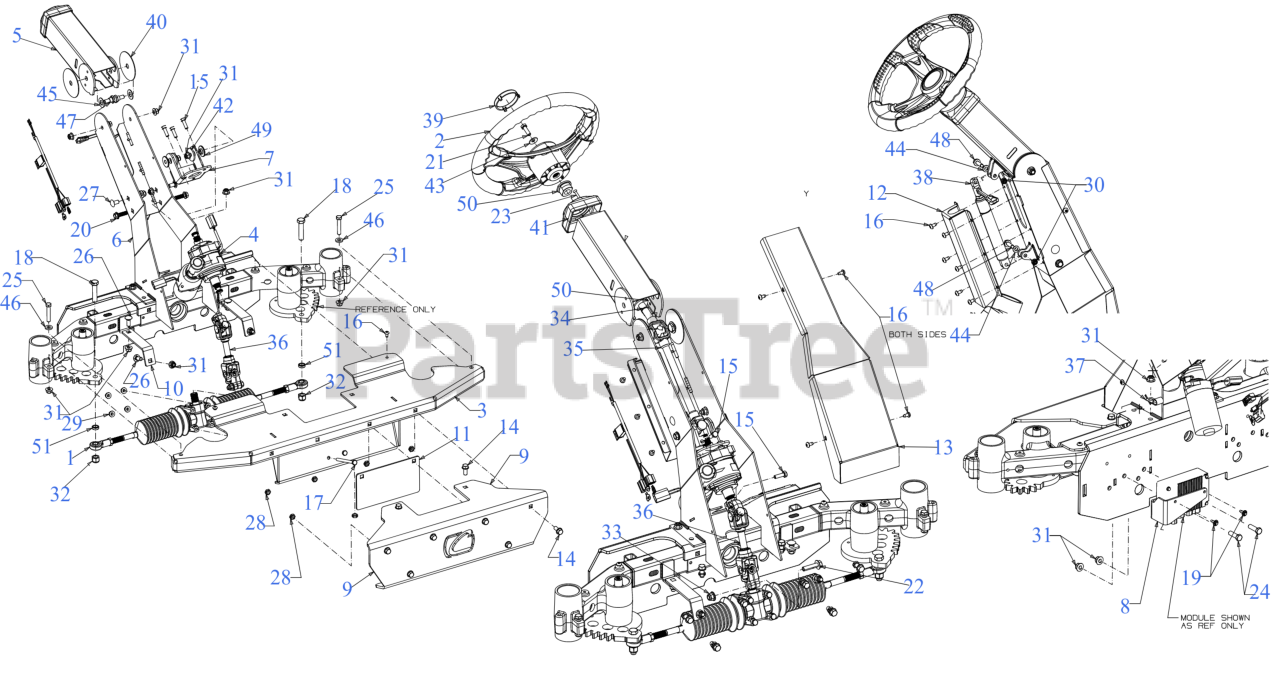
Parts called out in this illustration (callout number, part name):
1	STEERING GEARBOX
2	STEERING WHEEL
4	POWER STEERING CONTROL MODULE
4	POWER STEERING WIRE HARNESS
5	UPPER PIVOT COLUMN ASSEMBLY
7	EPS PIVOT BRACKET
8	STEERING MODULE MOUNTING BRACKET
9	FRONT BUMPER UPPER COVER
13	COLUMN COVER
14	SCREW 3/8-16 x .875 GR5
15	SCREW M8-1.25 x 25 GR8.8
16	SCREW 1/4-20 x .5
17	SCREW 5/16-18 x 4.00 GR5
18	SCREW 1/2-20 x 2.25
19	SCREW M6-1 x .625
20	SCREW 3/8-16 x 1.25 GR5
21	SCREW 5/16-18 x 1.00 GR5
22	SCREW 3/8-16 x 1.25 GR5
23	SCREW #10-16 x 1.25
24	SCREW 3/8-16 x 1.25 GR5
25	SCREW 3/8-16 x 2.0 GR5
26	CARRIAGE BOLT 3/8-16 x 1.00 GR5
27	CARRIAGE BOLT 3/8-16 x .75
28	JAM LOCK NUT
29	FLANGE LOCK NUT 5/16-18
30	FLANGE LOCK NUT
32	HEX NUT 1/2-20 GR8 NYLON
35	STEERING SHAFT TOP
36	LOWER STEERING SHAFT
37	J TYPE CLIP
38	TILT STEERING DAMPENING CYLINDER
39	STEERING WHEEL CAP
40	COLUMN PLATE
41	STEERING COLUMN COVER
42	FLAT WASHER
43	BELL WASHER .337 X.867 x .057
44	FLAT WASHER .344 x .62
45	TEFLON WASHER .565X1.20
46	FLAT WASHER
47	SHOULDER SCREW .498 DIA x .340
48	SHOULDER SCREW
49	SHOULDER SPACER
50	FLANGE BEARING
